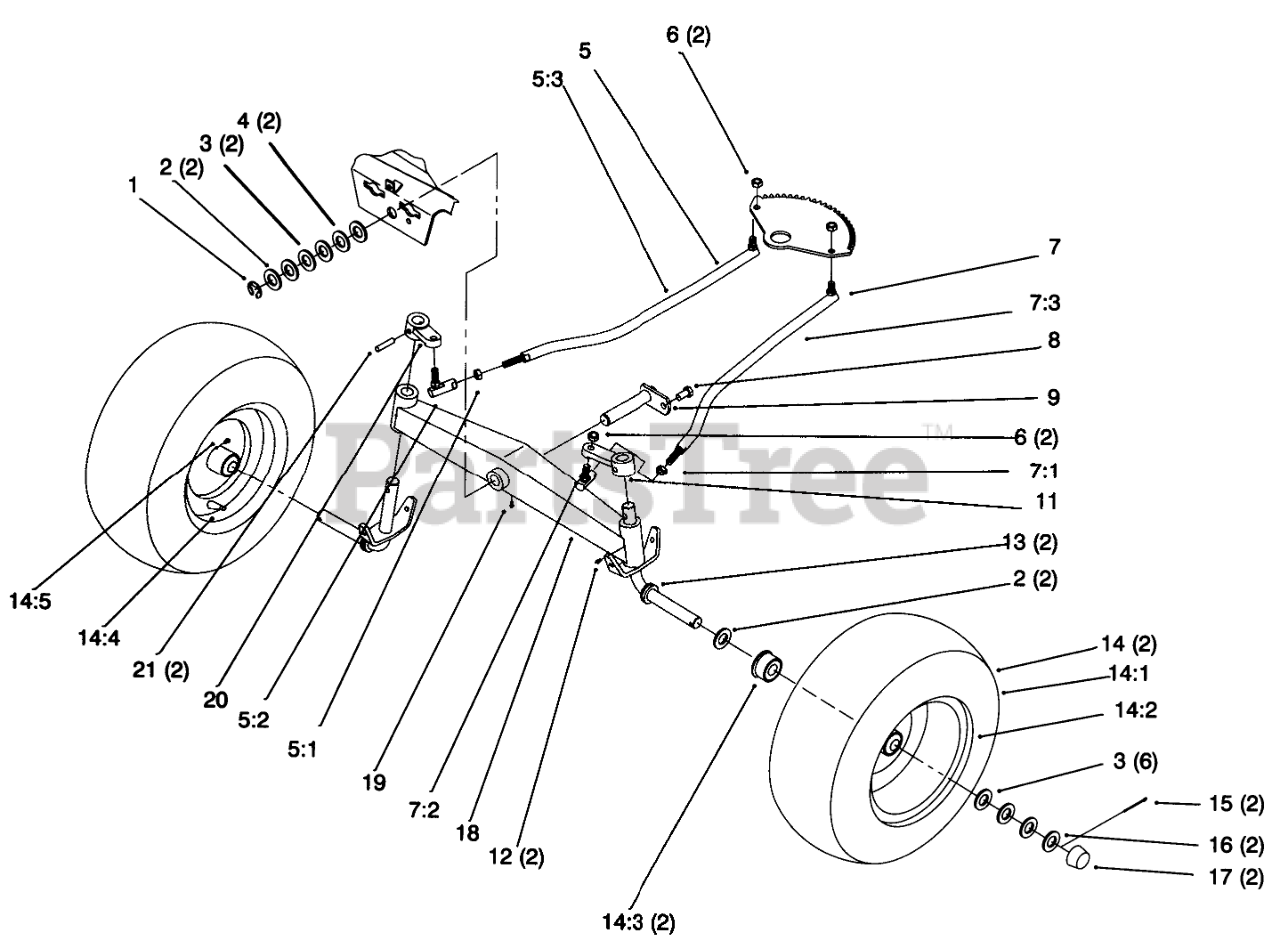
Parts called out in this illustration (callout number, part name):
1	E-RING
2	WASHER-SHIM
3	WASHER
4	Washer
5	LINKAGE-STEERING, RH
5:1	Nut-HJ
5:2	BALL-JOINT
5:3	Ball Link ASM
7	LINKAGE-STEERING, LH
7:1	Nut-HJ
7:2	BALL-JOINT
7:3	Ball Link ASM
8	SCREW-HWH, TAPTITE
9	PIN-AXLE
11	Arm-Front Spindle
12	FITTING-GREASE
13	SPINDLE
14	Wheel AND Tire ASM
14:1	Tire (16 x 6.5-8) 2-Ply -2 Wheel Axel
14:2	Wheel
14:3	BEARING-WHEEL
14:4	VALVE
14:5	ZERK-GREASE
15	PIN-COTTER
16	WASHER-PLAIN
17	CAP-HUB
18	AXLE-FRONT
19	FITTING-LUBE, 45 DEG
20	Arm-Front Spindle
